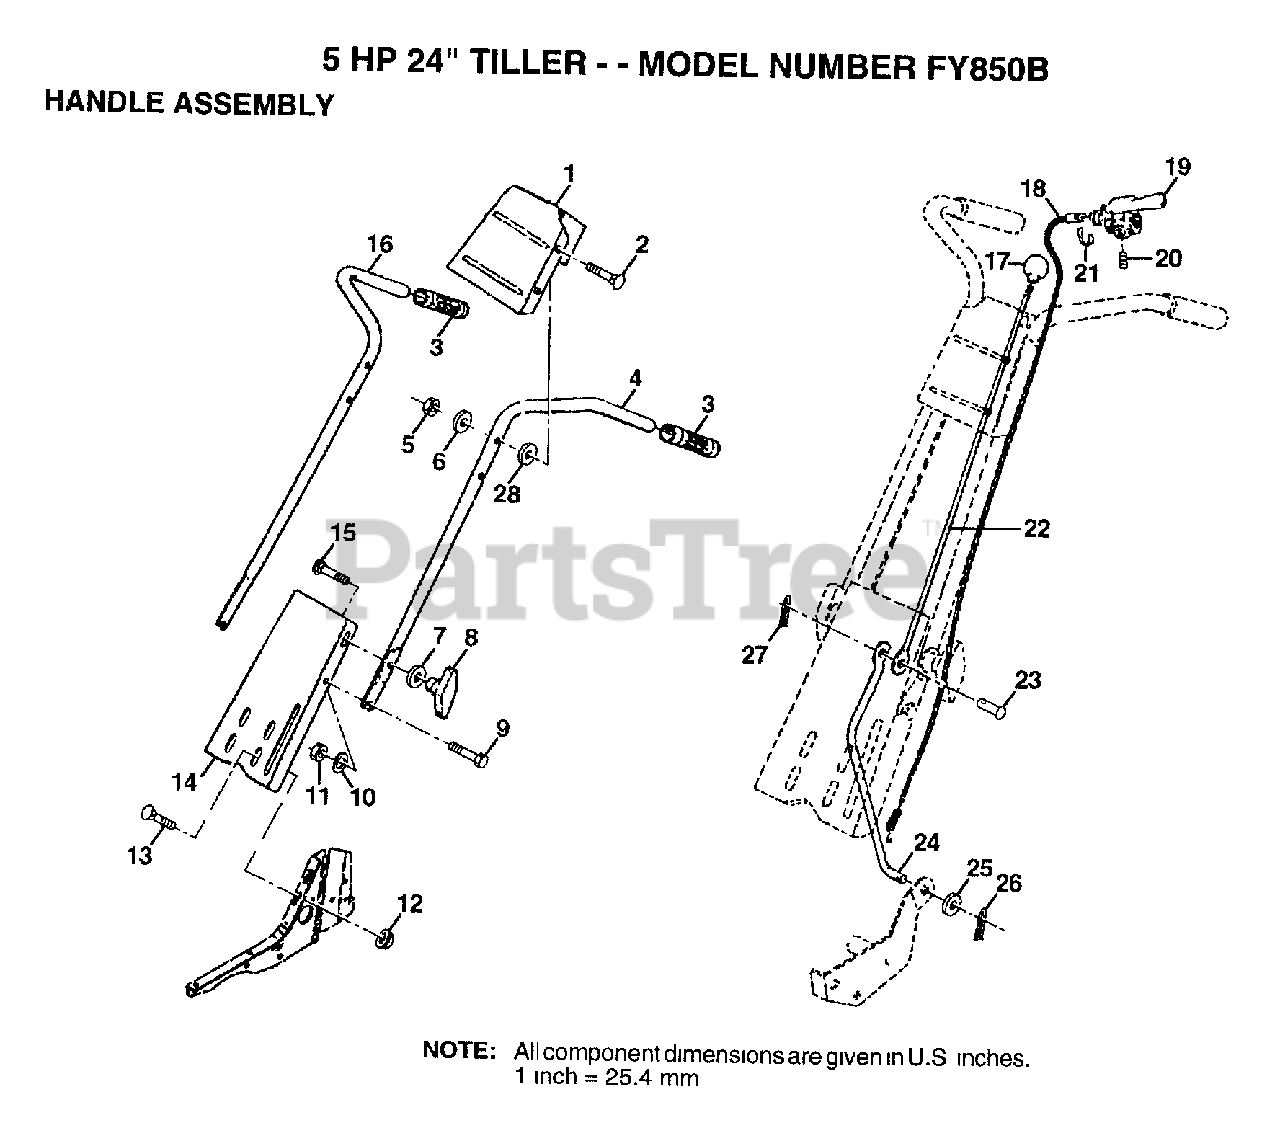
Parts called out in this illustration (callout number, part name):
1	HANDLE BRKT
2	BOLT
3	GRIP NUB DOUBLE
4	HANDLE PNT LH
6	WASHER
7	WASHER
8	KNOB HANDLE
10	LOCKWASHER
11	NUT.HEX.5/16-18
12	NUT
13	BOLT
15	BOLT
16	HANDLE PNT RH
17	KNOB T(3/8 HOLE)
18	CABLE CLUTCH T
19	CONTROL LEVER TI
20	SCREW
21	E-RING
22	ROD REVERSE TI
23	RIVET.RD.HD.DRILL
24	REVERSE ROD TI
25	WASHER
26	COTTER PIN
28	WASHER
